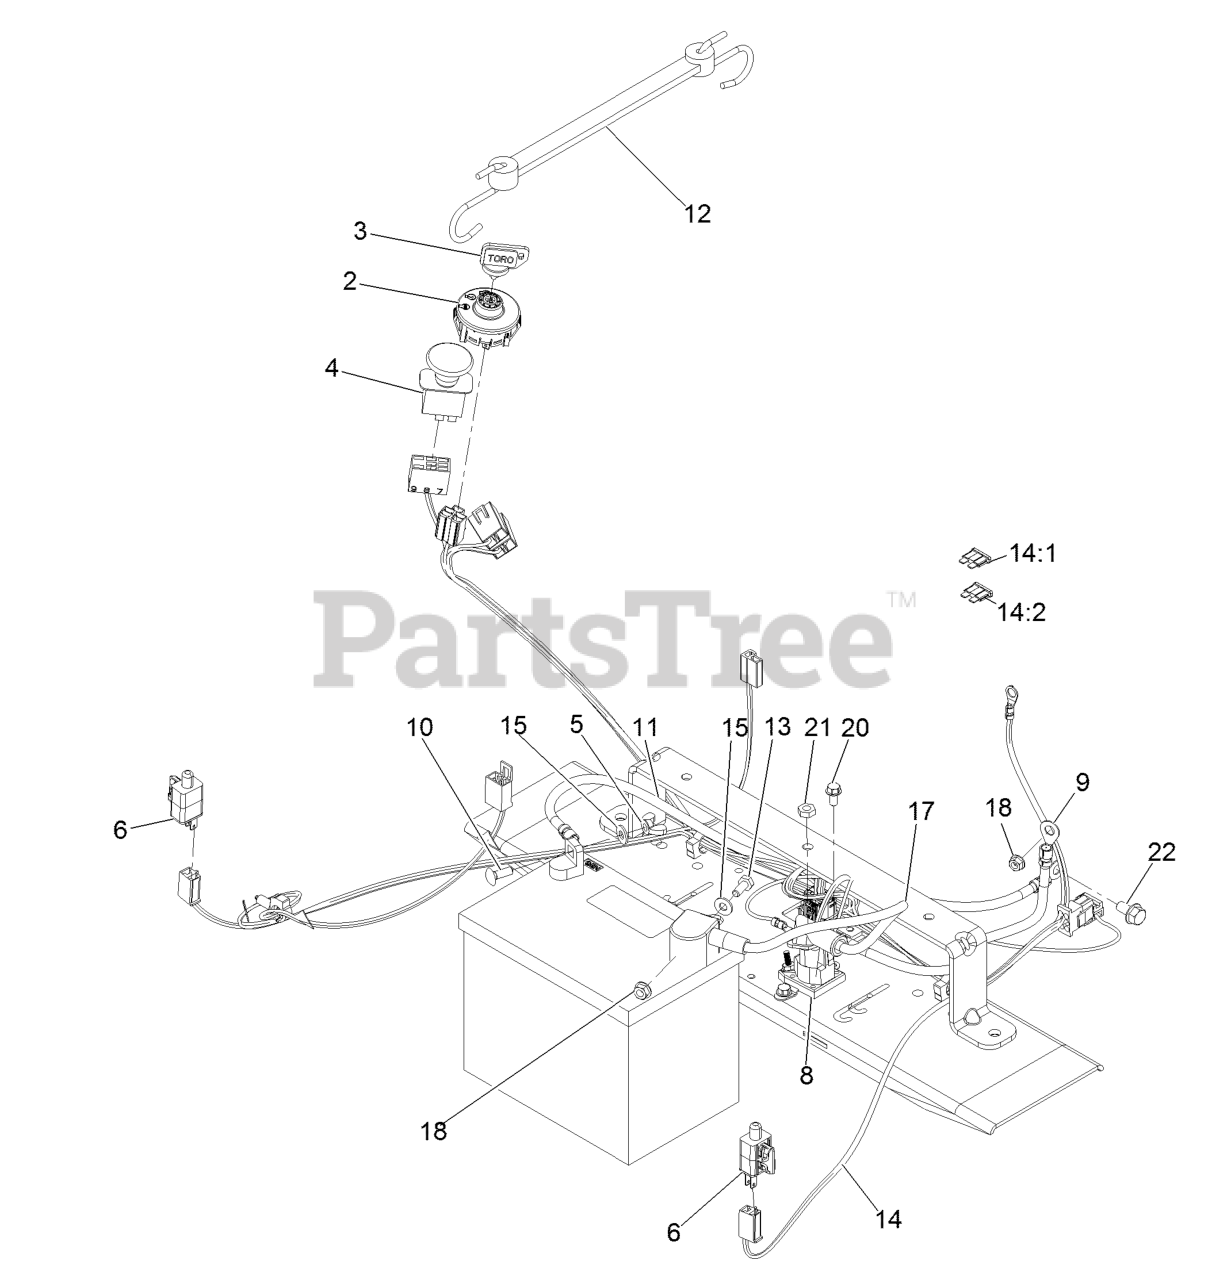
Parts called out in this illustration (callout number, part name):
3	KEY-IGNITION
4	SWITCH-PTO
5	NUT-WING
8	SOLENOID
9	CABLE-BATTERY, RED
10	BOLT-CARR
11	CABLE-BATTERY, BLACK
12	HOLDDOWN-BATTERY
13	SCREW-HH
14:1	FUSE-BLADE, 30 AMP
14:2	FUSE-BLADE, 25 AMP
15	WASHER-FLAT
17	CABLE-BATTERY, RED
20	SCREW-HWH
21	NUT-JAM
22	SCREW-HHF
